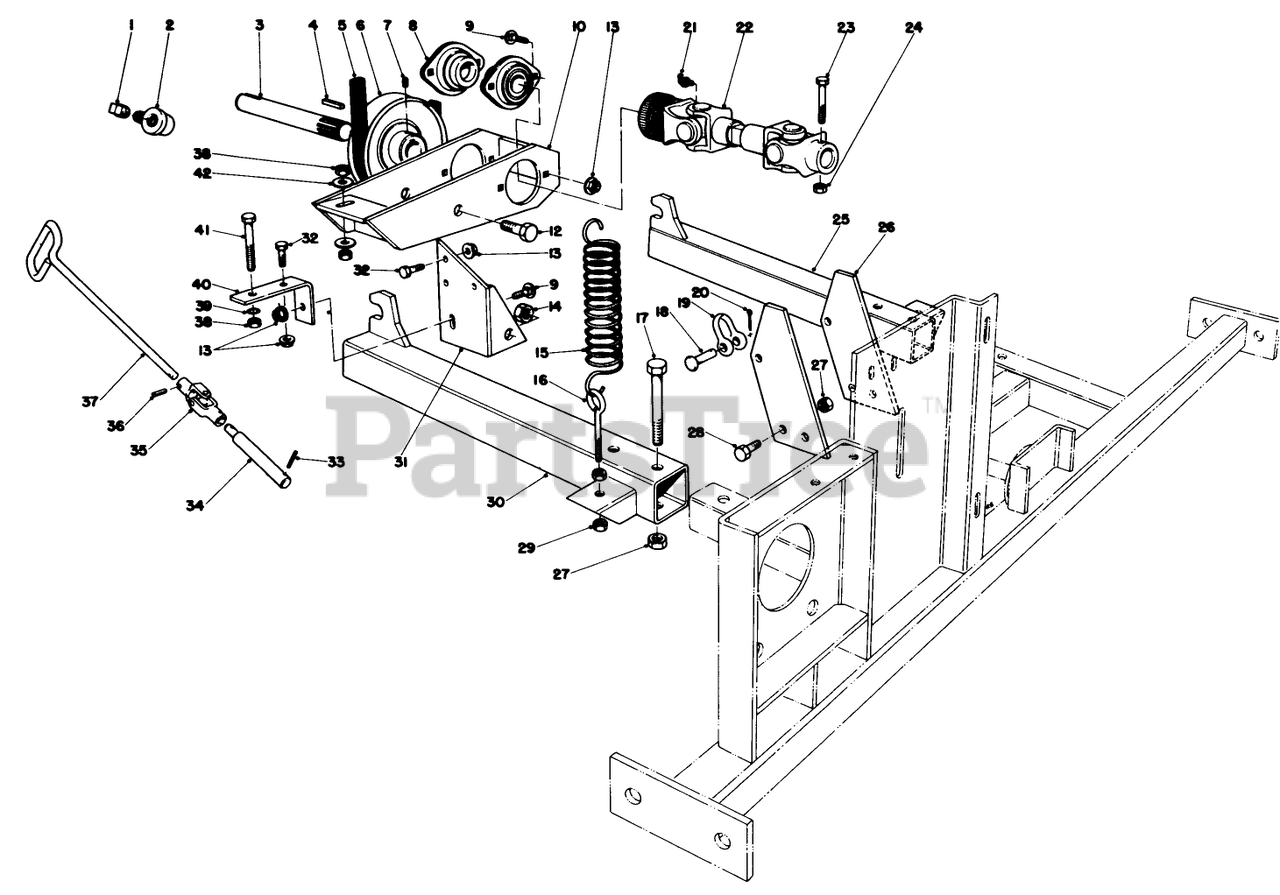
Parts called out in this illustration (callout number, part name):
1	PLUG-PIPE, SQH
2	Elbow
3	Jackshaft
5	V-Belt
6	Pulley
7	Setscrew
8	Bearing
9	STEP BOLT
10	Bearing Support
12	SCREW-HH
13	NUT-HF
14	1/2-13 CONELOCK NUT
15	Extension Spring
16	Eyebolt
17	SCREW-HH
18	PIN-CLEVIS
19	SHACKLE
20	PIN-COTTER
21	Grease Fitting
22	Power Take Off Shaft
23	SCREW-HH
24	NUT-HEX, SIDE DEFORM
25	Tool Bar L.H.
26	Lifting Lug
27	NUT-LOCK, CONE
28	SCREW-HH
29	NUT-HEX
30	Tool Bar R.H.
31	Hinge Plate
32	SCREW-HH
33	PIN-SPRING
34	Pin Connector
35	Universal Joint
36	PIN-ROLL
37	Rod-Spout Control
38	NUT-HEX
39	WASHER-LOCK
40	Angle Support
41	SCREW-HH
42	WASHER-FLAT
